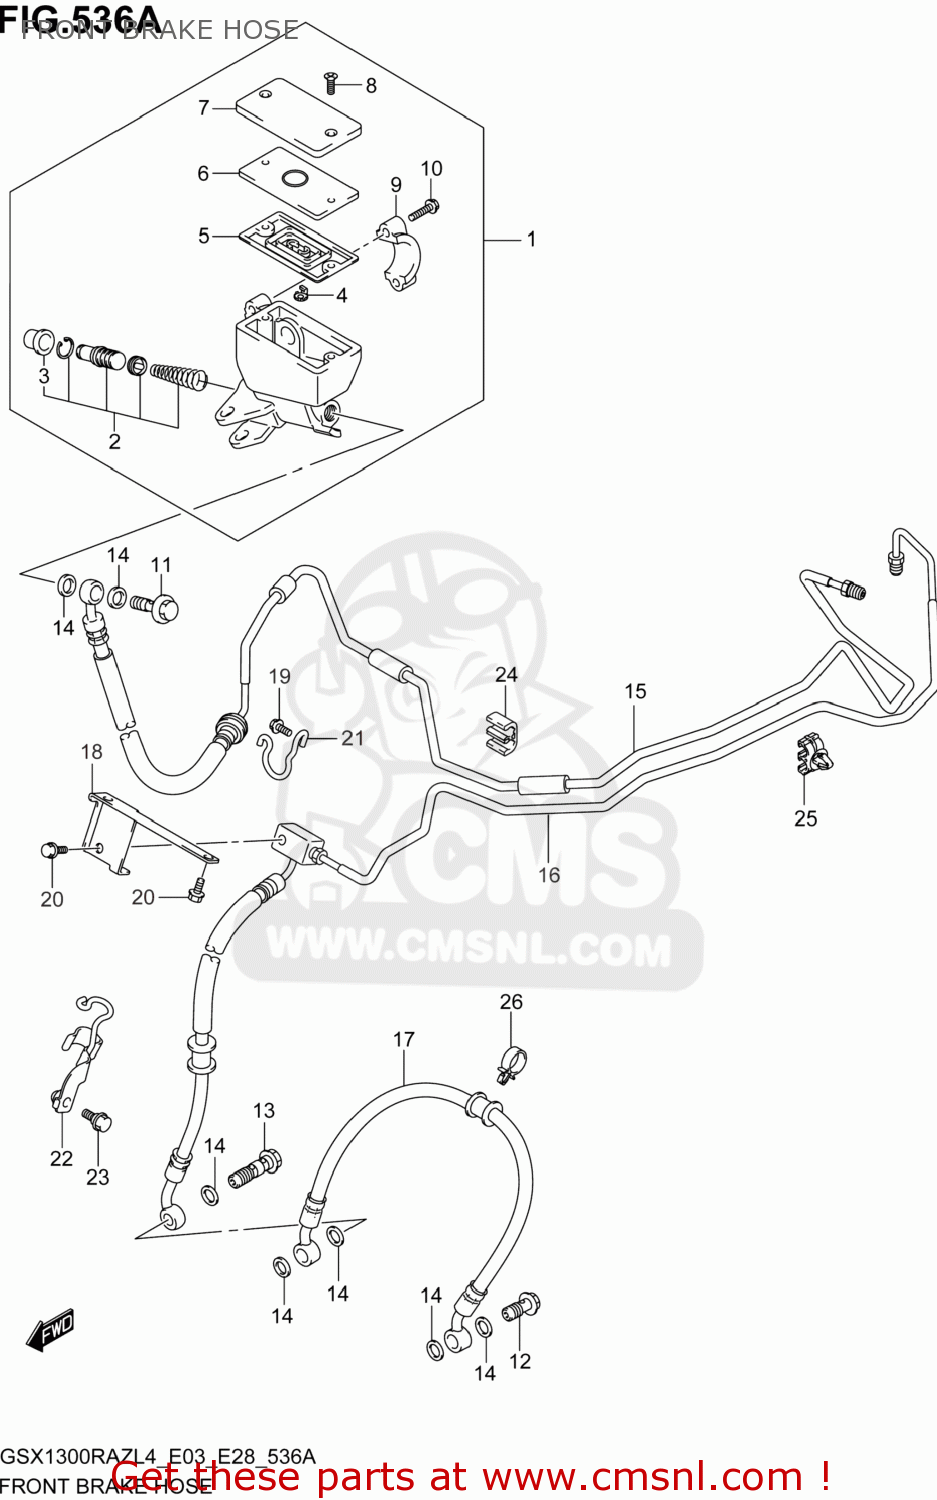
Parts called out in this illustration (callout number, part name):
1	CYLINDER ASSY,FRONT MASTER
2	PISTON & CUP SET
3	BOOT
4	PROTECTOR
5	6
6	PLATE,DIAPHRAGM
7	CAP
8	SCREW
9	HOLDER
10	BOLT
11	BOLT UNION
12	BOLT UNION
13	BOLT UNION
14	WASHER(10X15X1.5)
15	HOSE ASSY,FR BRAKE NO.1
16	HOSE ASSY,FR BRAKE NO.2
17	HOSE,FR BRAKE NO.2
18	BRACKET,BRAKE HOSE
19	BOLT
20	BOLT
21	CLAMP,BRAKE HOSE
22	CLAMP,FR BRAKE HOSE
23	BOLT(6X12)
24	CLAMP
25	CLAMP
26	CLAMP
